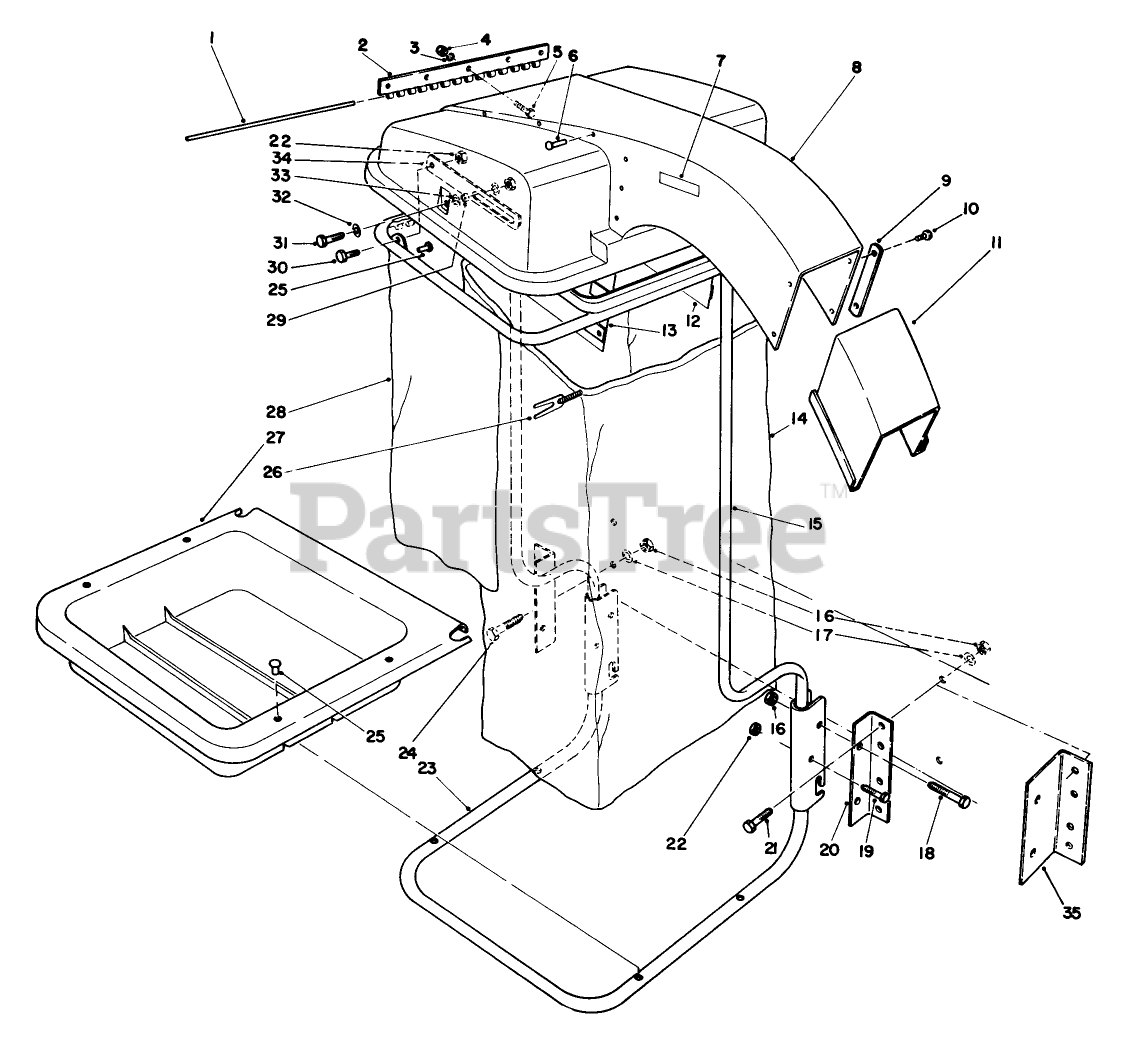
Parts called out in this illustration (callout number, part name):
1	HOOD HINGE PIN
2	Hinge Half
3	WASHER-FLAT
4	NUT-LOCK, NI
6	RIVET-BLIND
7	Decal-Caution
8	Hood Assembly (Incl. Ref. #7)
9	PLATE-NUT B
10	SCREW-HSBH
11	Extension-Snout
12	Screen Left Hand
13	Screen Right Hand
14	BAG-CLOTH, 32"
15	Upper Support Tube Assy. (Incl. Ref. #25 & 28)
16	NUT-LOCK, CONE
17	WASHER-FLAT
18	SCREW-HH
19	SCREW-HH
20	BRKT-FRAME B
21	SCREW-HH
22	NUT-LOCK, CONE
23	Lower Support Tube Assy. (Incl. Ref. #25 & 27)
24	SCREW-HH
26	BAG CORD FASTENER
27	Tray-Lower
28	Skirt-Bagging Frame
29	SPACER - PIVOT ARM
30	SCREW-HH
31	SCREW-HH
32	WASHER-FLAT
33	WASHER-FLAT
34	Stop-Hood
35	Bracket-Frame (Use with 62" Blower Kit
